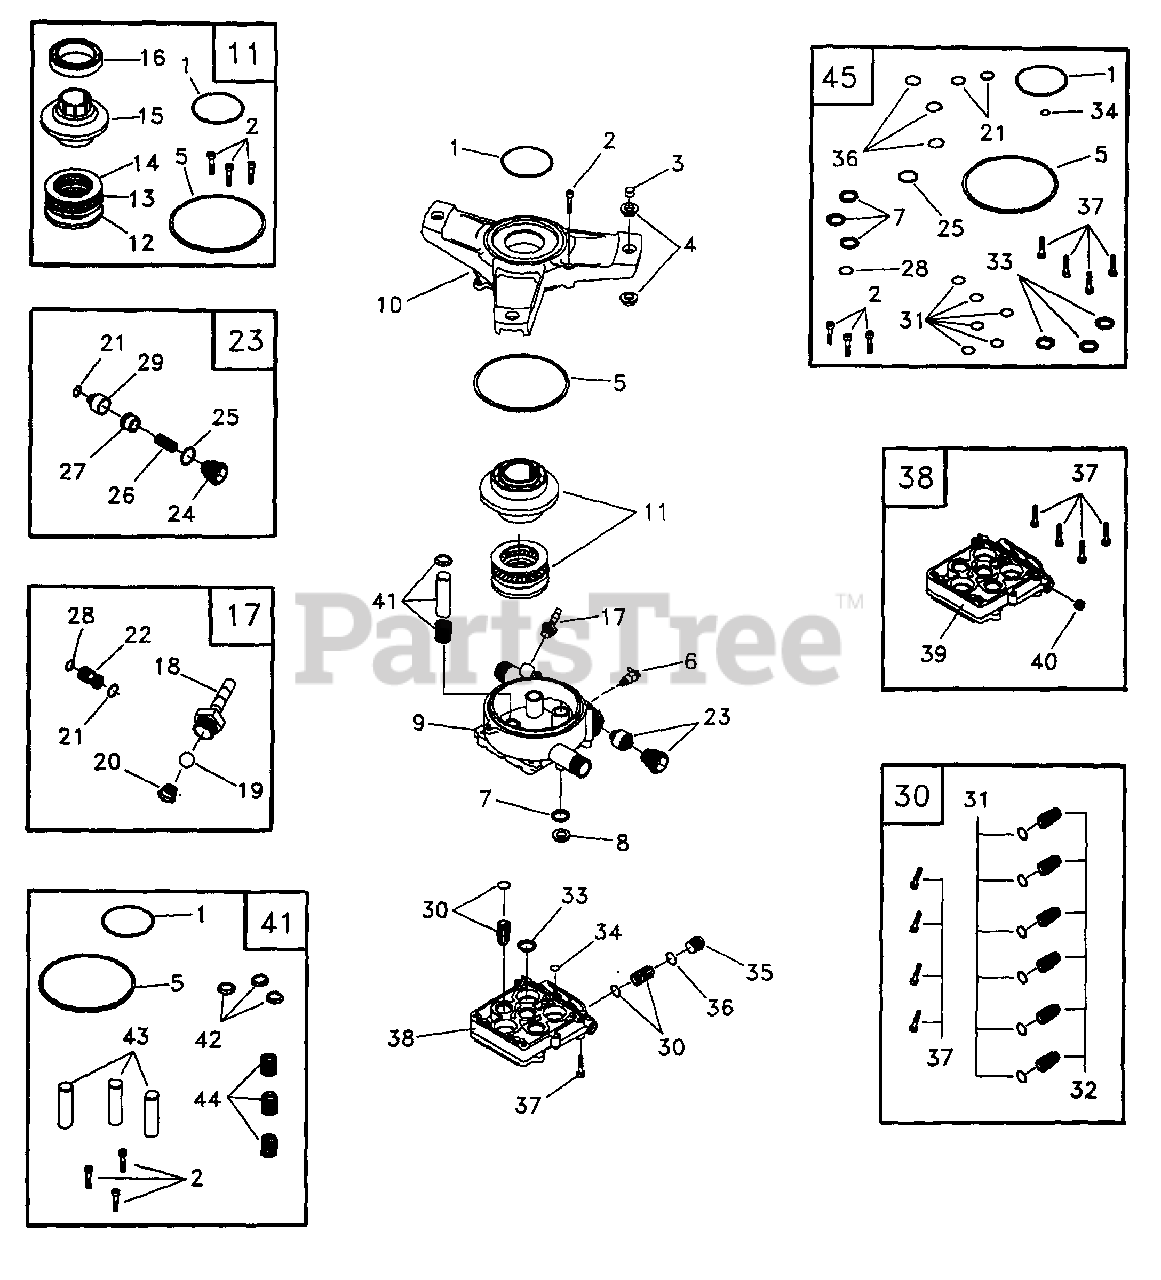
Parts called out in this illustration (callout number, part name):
1	SEAL, Engine Donut
2	SHCS, M6-1 x25
2	SHCS, M6-1 x 25
3	SLEEVE, Grommet Spacer
4	BUSHING, Rubber Mount
5	O-RING, Housing Seal
6	THERMAL RELIEF
7	SEAL, Oil Piston 15 TC4
8	SPACER, Pilot
9	HOUSING, Piston
10	ADAPTER, Engine
11	KIT, AXIAL CAM SERV
12	WASHER, Brg. 36 x 65 x 6Thk
13	ASSY., Brg. Cage 45 x 65
14	WASHER, Brg. 45 x 65 x 1
15	CAM, Axial 5.6 VS
16	BALL BEARING, 35 x 72 x 17
17	KIT, CHEM INJECT
18	FITTING, Chem Inject
19	BALL, Chem Inject
20	SPRING, Chem Inject
21	O-RING, Venturi & Seat, Black
21	O-RING, Venturi L Seat, Black
22	VENTURI, Chem Inject
23	KIT, UNLOADER
24	CAP, Unloader
25	O-RING, Unloader Cap
26	SPRING, 2000 Unloader
27	PISTON, Unloader
28	O-RING, Venturi, Yellow
29	SEAT, 2000 Unloader
30	KIT, CHECK VALVES
31	O-RING, Check Valve
32	ASSY., Check Valve
33	SEAL, Double-Lip
34	O-RING, Hi-Pressure Transfer
34	O-RING, High Pressure Transfer
35	CAP, Outlet Check Valve
36	O-RING, Outlet CV Cap
37	SHCS, M6-1.0 x 35
38	KIT, HEAD CASTING SFG
39	HEAD, Pump
40	PLUG, 1/8-28 W/VIBR
41	KIT, PISTON & SPRING
42	RETAINER, Piston Spring
43	PISTON, Dia. 15 x 65
44	SPRING, Piston Return
45	KIT, O-RING/SEAL SERV
